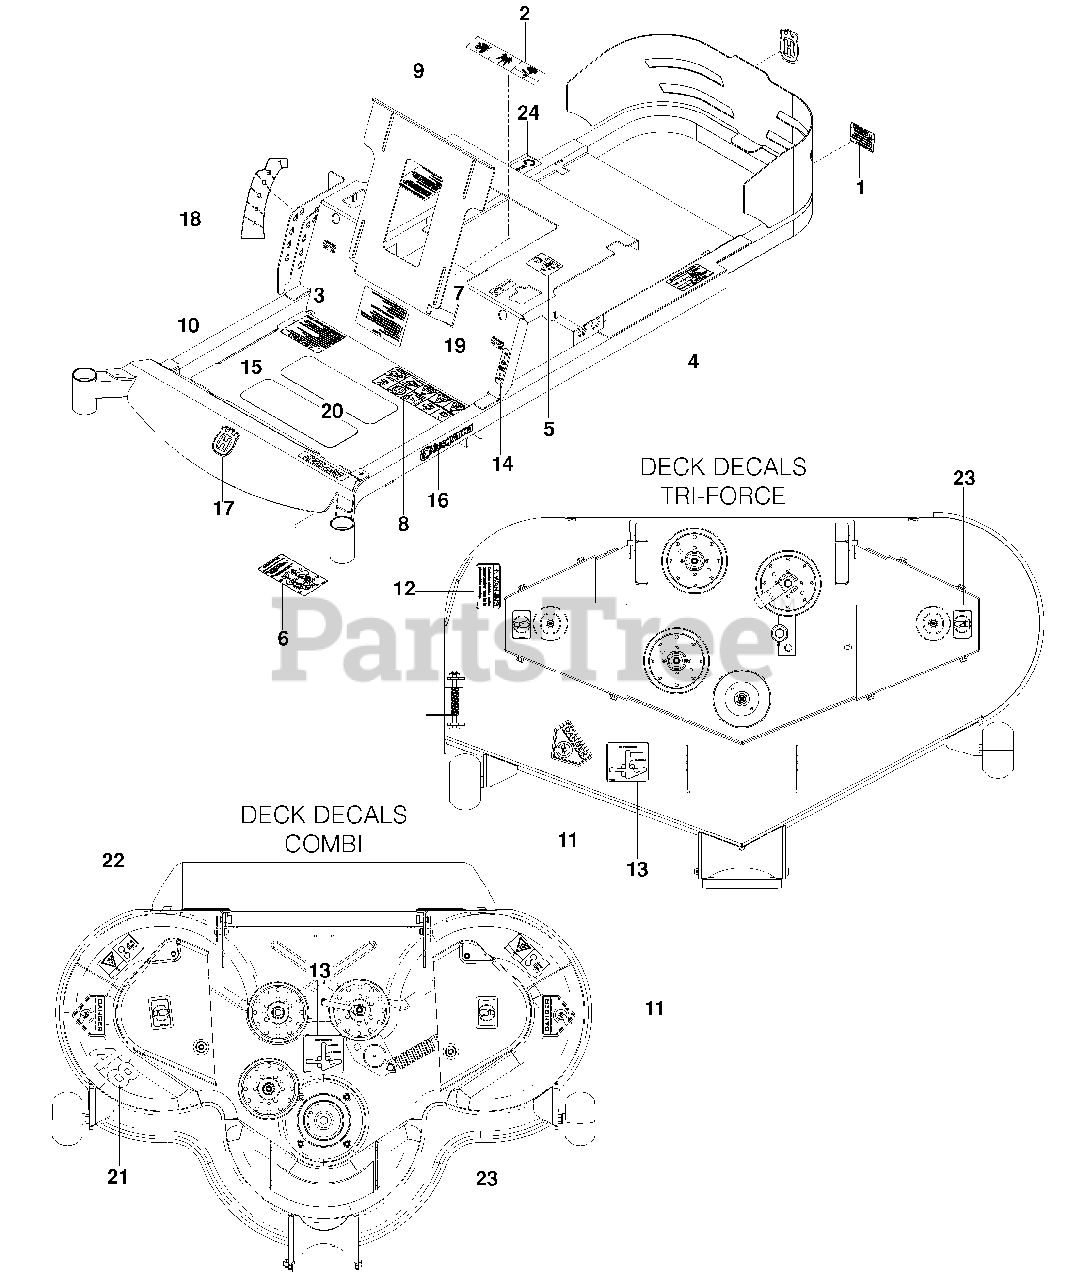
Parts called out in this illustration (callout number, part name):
1	DECAL, PROP 65
2	DECAL, BATTERY WARNING
3	DECAL, START
4	DECAL, DO NOT TOW
5	DECAL, EXIT MOWER
6	DECAL, SERVICE
7	DECAL, MOTION CONTROL
8	DECAL, SAFETY WARNING
9	DECAL, RESPONSIBILITY
10	DECAL, WARNING
11	DECAL, DANGER
12	DECAL, WARNING
13	DECAL, BELT ROUTING
14	DECAL, PARK BRAKE
15	ABRASIVE PAD
16	DECAL, HUSQVARNA
17	DECAL, CROWN H
18	DECAL, HEIGHT
19	DECAL, TRACKING
20	DECAL, EZ4824
21	DECAL, 48"
22	DECAL, BELT DRIVES
23	DECAL, NO STEP
24	DECAL, ECM AUSTRALIA
